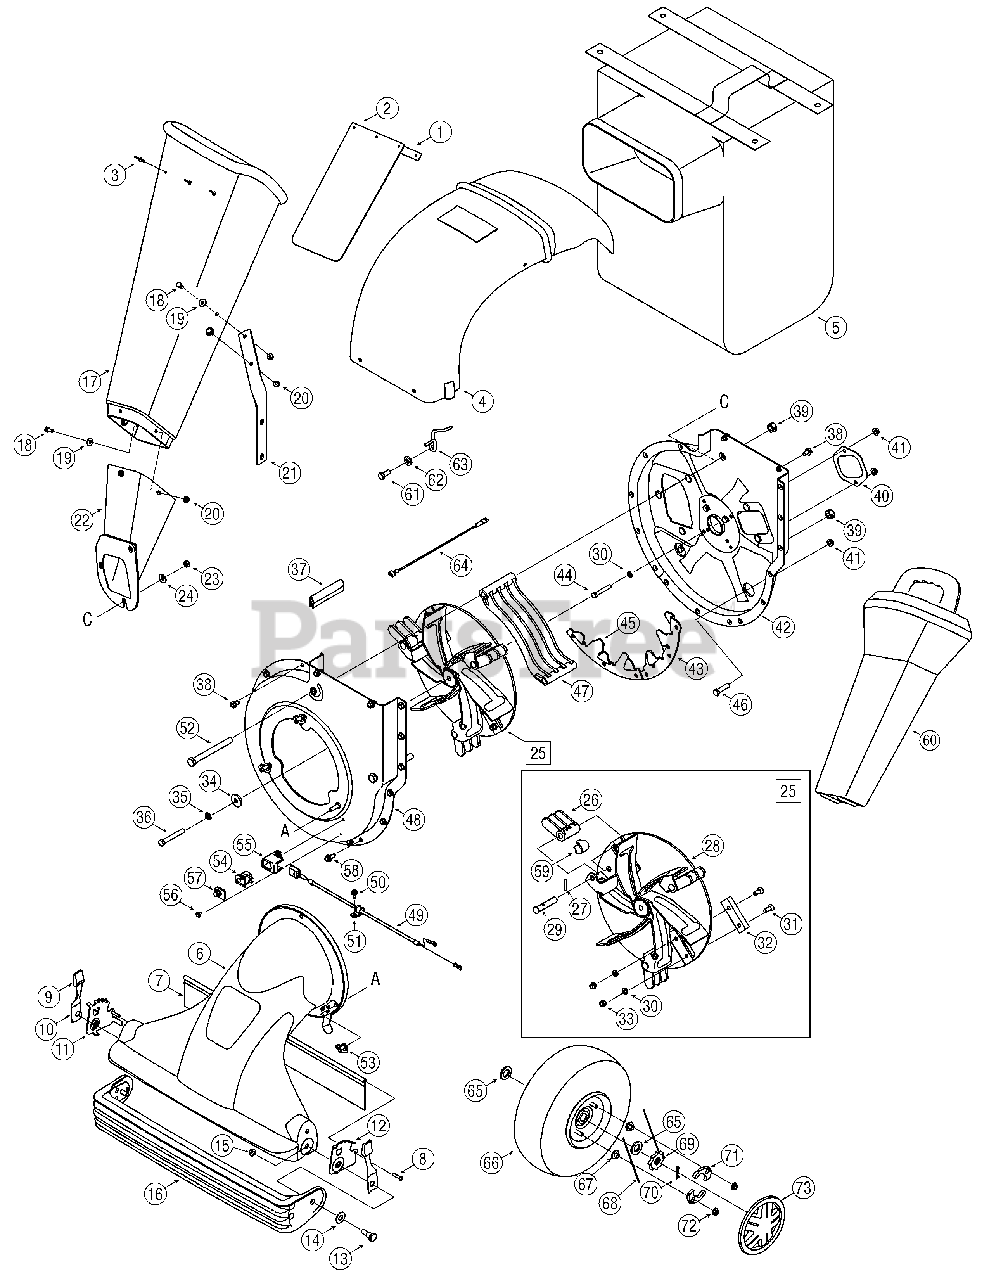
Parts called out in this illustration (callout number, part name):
1	Chute Flap Strip
2	Chute Flap
3	Pop Rivet
4	Discharge Chute
5	Bag
6	Nozzle Assembly
7	Nozzle Flap
9	Height Adjustment Knob
10	Spring Lever
13	Shoulder Screw
14	Flat Washer.510 x 1.12 x.060
15	Hex Flange Lock Nut 3/8-16
16	Door Assembly
17	Chipper Chute
18	Hex Cap Screw 1/4-20 x.620
19	Flat Washer.28 ID x.74 OD
20	Hex Lock Nut 1/4-20
23	Hex Nut, 5/16-18
24	Belleville Washer,.340ID x.872OD
25	Impeller Assembly: Complete
26	Flail Blade
27	Spiral Pin
28	Impeller Assembly
29	Clevis Pin
30	Lock Washer 5/16
31	Cap Screw 5/16-24 x 1.0
32	Chipper Blade
33	Hex Lock Nut 5/16-24
34	Flat Washer.406 x 1/1/4
35	Lock Washer 3/8
36	Hex Cap Screw 3/8-24 x 2.75
37	Rubber Seal
38	Hex Washer Screw 5/16-18
39	Hex Lock Nut 1/2-13
41	Hex Flange Lock Nut 5/16-18
44	Hex Cap Screw 5/16-18 x 2
46	Hex Cap Screw 5/16-18 x.75
47	Discharge Screen
49	Wire Harness
50	TT Screw 1/4-14 x 0.625"
52	Hex Cap Screw 1/2-13 x 5.0
53	Knob 5/16-18
54	Switch
55	Safety Switch Mounting Cover
56	Hex Washer Screw
57	Switch Cover
58	LD Screw 5/16-18 x 0.75"
59	Retaining Pin Clip
60	Tamper Plug (If Equipped)
61	Hex Cap Screw 5/16-24 x.75
62	Flat Washer.344 x.75 x.12
63	Belt Keeper
64	Adapter Harness Assembly
65	Flat Washer 5/8 ID x 1.0 OD
66	Wheel Complete 10 x 4 x 4
67	Hex Nut 1/4-20
68	Plastic Spring Ratchet
69	Wheel Ratchet 1.62 OD x.5 serr
70	Cotter Pin
71	Pawl LH.345 ID
71	Pawl RH.345 ID
72	Hex Flanged Lock Nut 1/4-20
